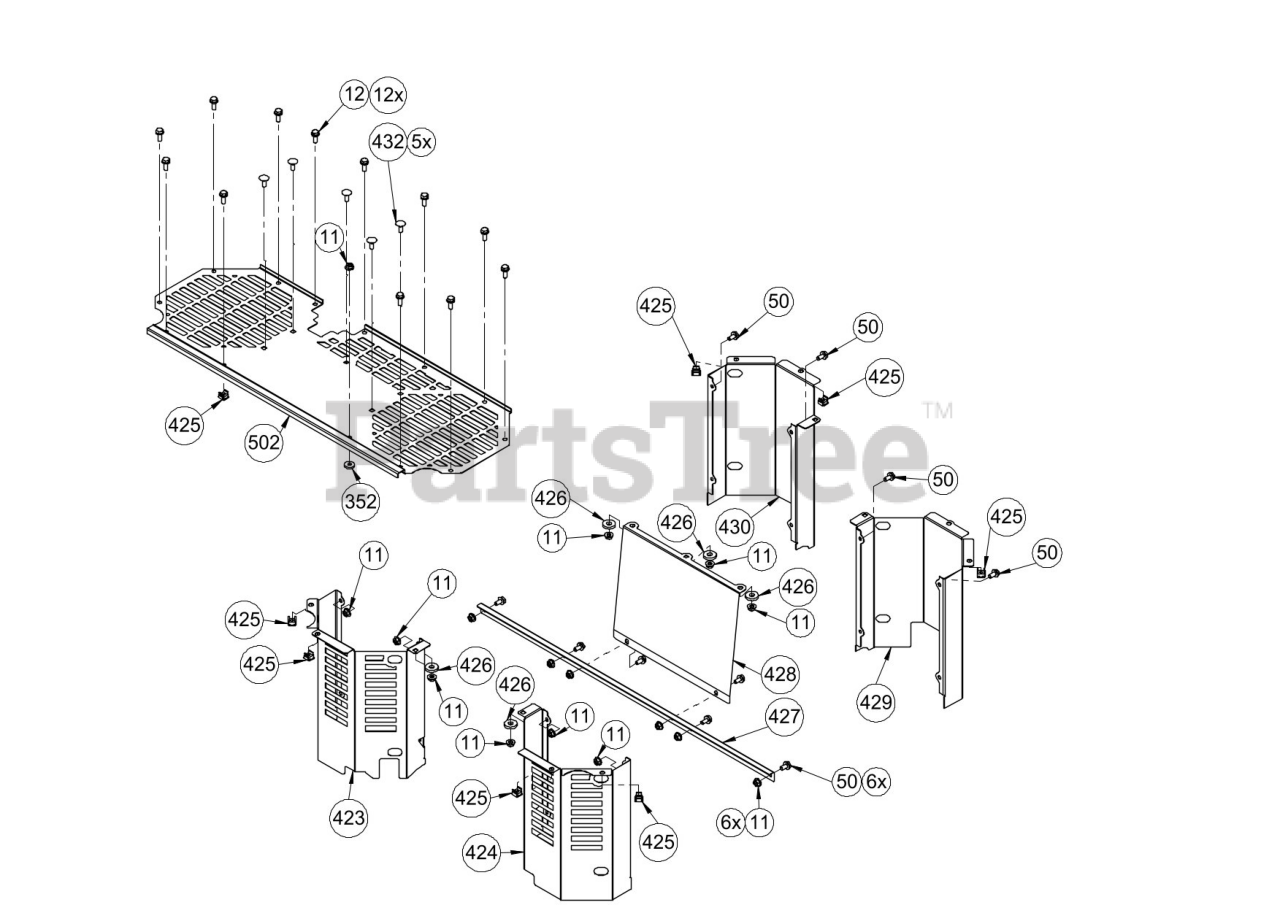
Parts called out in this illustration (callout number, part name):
11	NUT, FLG SLF LK M6 CL 8 ZCC
12	NUT, FLG SLF LK M6X16
50	BLT, FLG SLF LK M6X12
352	WSHR, FLT M6.4 DIN 7349 ST ZCC
423	AIR DUCT, REAR LEFT
424	AIR DUCT, REAR RIGHT
425	NUT, CAGE M6
426	WSHR, FLT M8.4 DIN 7349 ST ZCC
427	CROSS BRACE
428	SHIELD, HEAT
429	AIR DUCT, FRONT RIGHT
430	AIR DUCT, FRONT LEFT
432	BLT, RHSN M6X16 DIN 603 8-8 ZCC
502	COVER, AIR DUCT W/ DECAL
